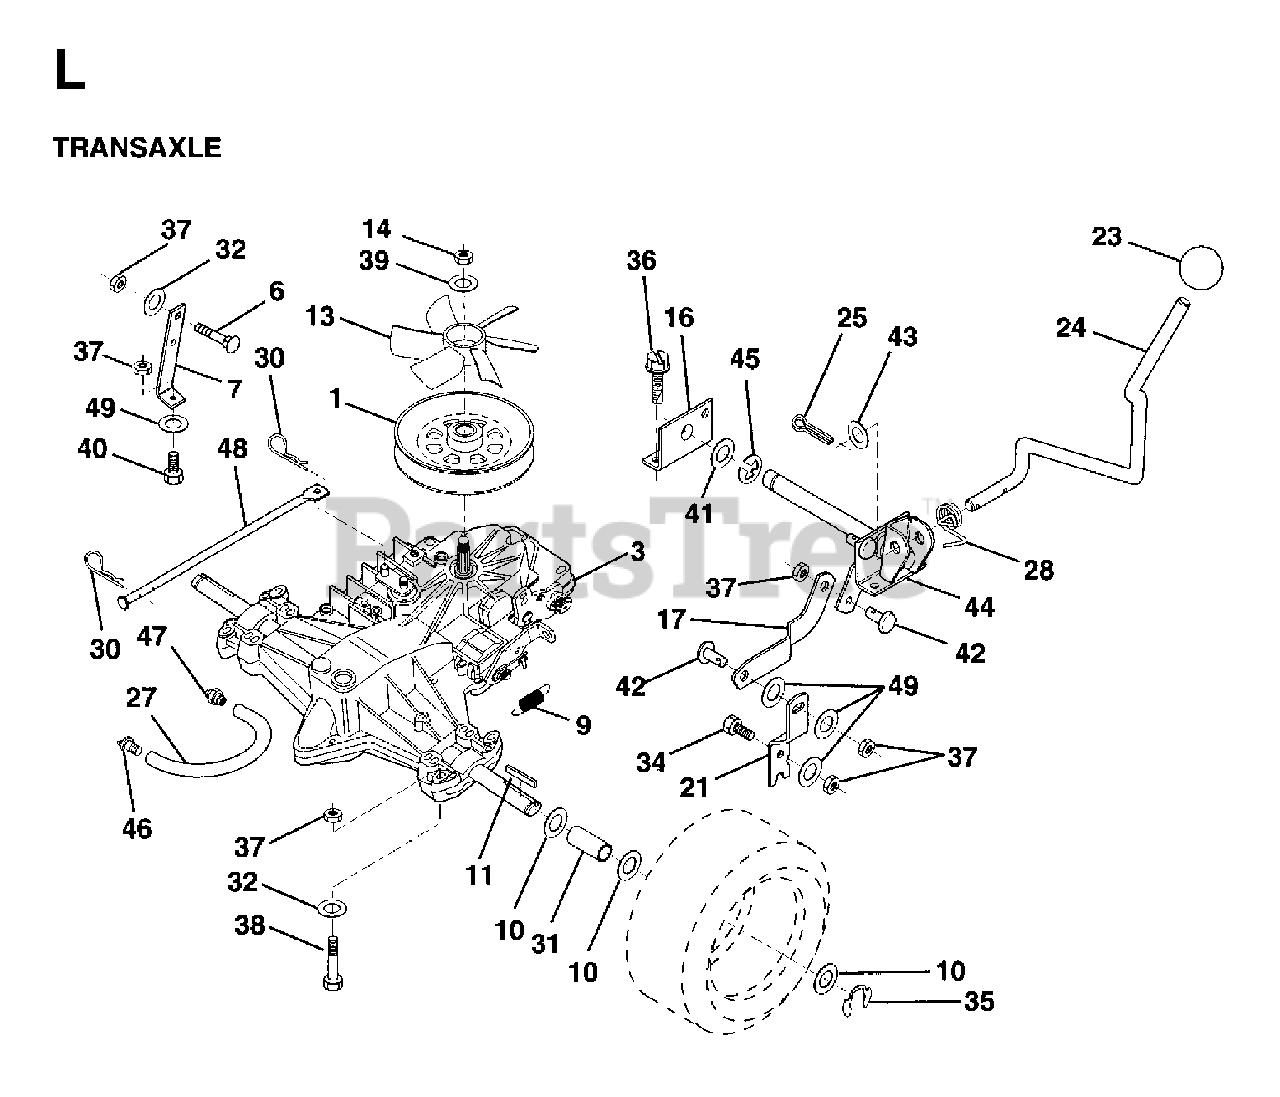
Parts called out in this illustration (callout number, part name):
3	TRANSAXLE HYDRO
6	BOLT
9	SPRING,BRAKE RETURN
11	SQUARE KEY
13	FAN.TRANSMISSION.HYDRO.6"
16	SUPPORT, SHIFT HANDLE
17	LINK, SHIFT
21	LEVER, SHIFT
23	KNOB.DELUXE.(PISTOL.GRIP).BLAC
24	ROD, SHIFTER
25	PIN COTTER
27	FUEL LINE
28	SPRING, TORSION
30	RETAINER M
31	SPACER SPLIT
32	WASHER
34	BOLT RB
35	E-RING LT
36	SCREW
37	NUT.71038.31-18.HEX.NYLOCK
38	BOLT HEX 5/16-18 GR 5
40	BOLT
43	WASHER
44	SHAFT PIVOT ASMBLY
45	RETAINING RING LT
48	ACTUACTOR
49	WASHER M
